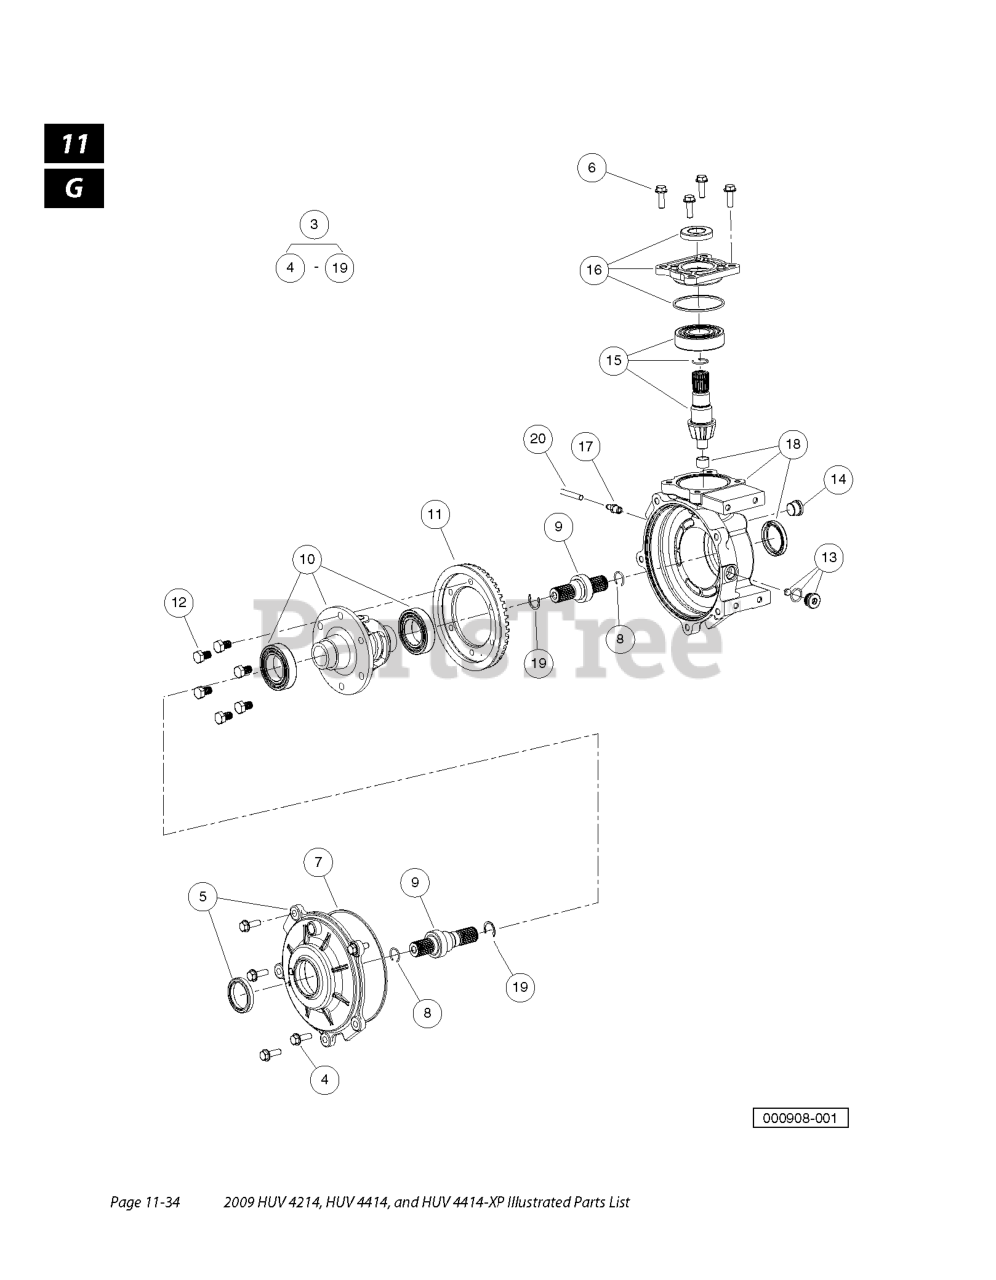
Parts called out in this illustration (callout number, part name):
3	DIFF, FRONT, OPEN, HILLIARD
4	BOLT FLG, 3/8-16X1.0 LOCTITE
5	ASSEMBLY, OUTPUT COVER
6	KIT, COVER BOLT
8	KIT, EXTERNAL RETAINING RING
9	KIT, STUB SHAFT
10	KIT, OPEN DIFFERENTIAL
12	KIT, RING GEAR BOLT
13	ASSEMBLY, DRAIN PLUG
14	PLUG, 3/4-16 HOLLOW HEAD
15	KIT, PINION GEAR
16	KIT, INPUT COVER
17	VENT FITTING
18	KIT, GEARCASE ASSEMBLY
19	KIT, INTERNAL RETAINING RING
20	HOSE, VENT, YELLOW, FRONT DIFF
